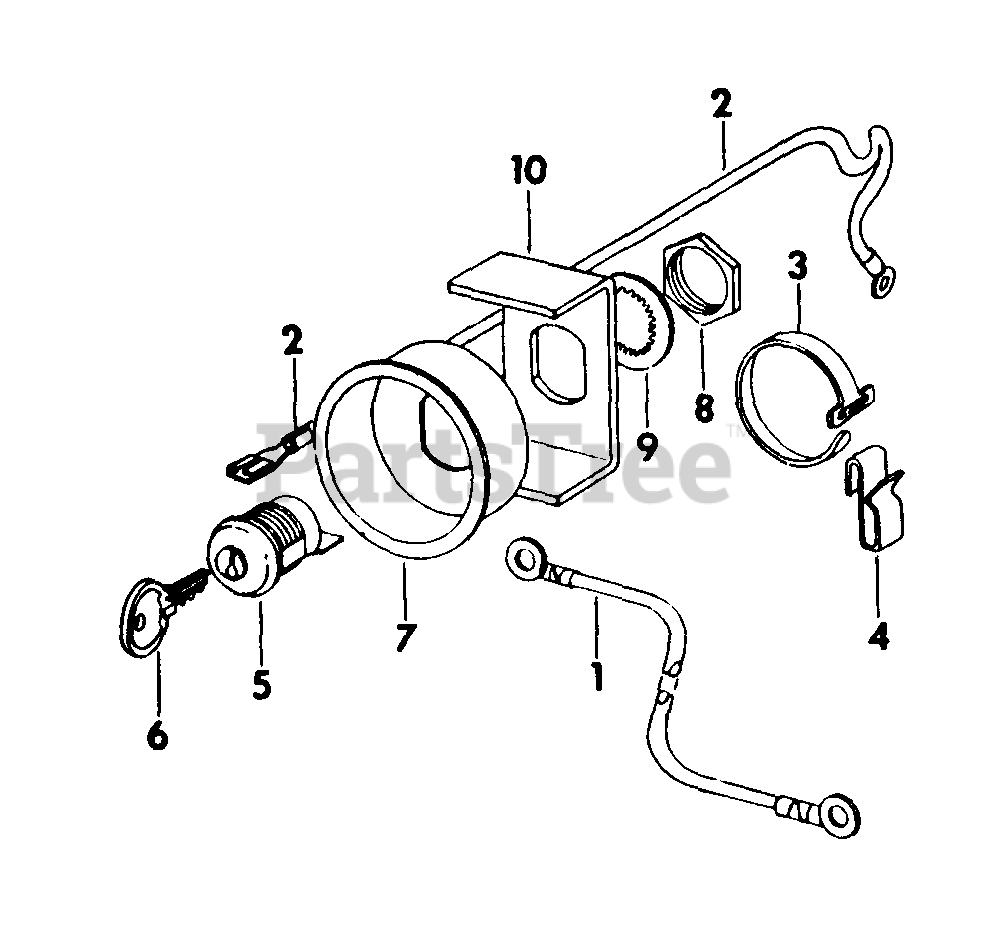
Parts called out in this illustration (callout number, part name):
1	CABLE ASSY, SWITCH TO GROUND
2	CABLE ASSY, MAGNETO GROUND
4	CLIP, CABLE SPEED
5	SWITCH, IGNITION KEY
6	KEY, IGNITION SWITCH
7	SOCKET, IGNITION SWITCH
8	NUT, MAGNETO IGNITION KEY MOUNTING
9	WASHER, MAGNETO IGNITION KEY MOUNTING
10	RETAINER, IGNITION SWITCH
